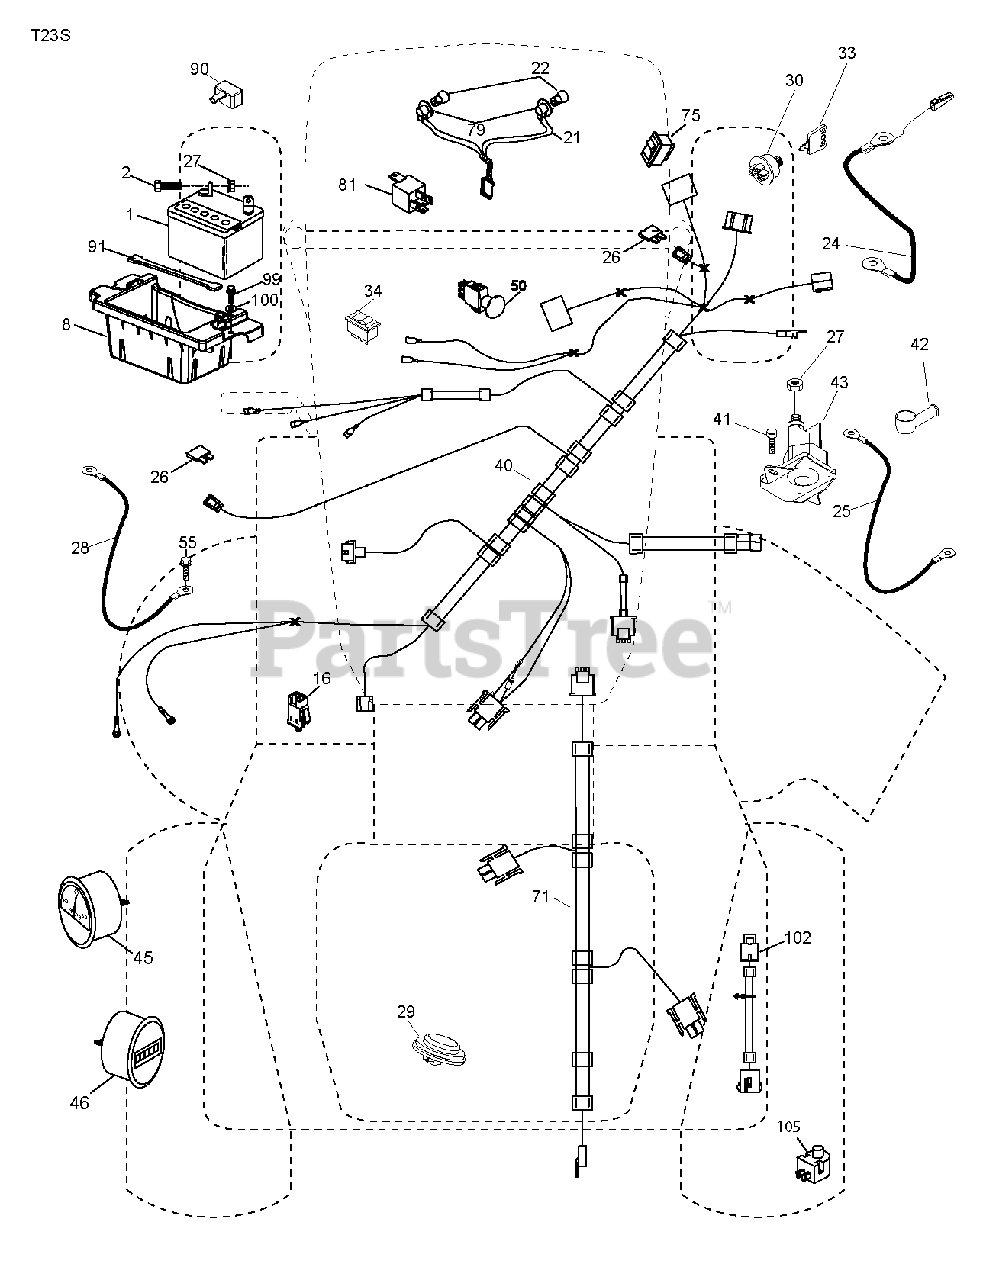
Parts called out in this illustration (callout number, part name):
2	BOLT LT
8	BOX, BATTERY MOUNT
16	SWITCH INTERLOOK PUSH-IN
21	HARNESS SOCKET LIGHT
22	LIGHTBULB
24	CABLE.BTRY.PSWRE.DSH.S
25	CABLE.STARTER.6G.BL/RED.17.5
26	FUSE 20AMP
28	CABLE GROUND 6 GA 21" 90T BLK
29	SWITCH.SEAT.DELTA.OPC.
30	IGNITION SWITCH
33	KEY/CHAIN.BLISTER.PACK.GEN.USA
34	SWITCH LT
40	HARNESS.DASH.
43	SOLENOID.W/BRASS.PLUNG
45	AMMETER.ROUND.SNAPIN
46	HOURMETER.ROUND.SNAPIN
50	PTO SWITCH
71	HARNESS
75	SWITCH.ROCKER.DECKLIFT
79	BULB HOLDER ASM.
81	RELAY HARNESS.SEALED
91	STRAP, BATTERY MOUNT
99	SCREW HEXWSHR 1/4-20X3/4
102	HARNESS PIGTAIL PCH TEX ROS
105	REVERSE SWITCH
